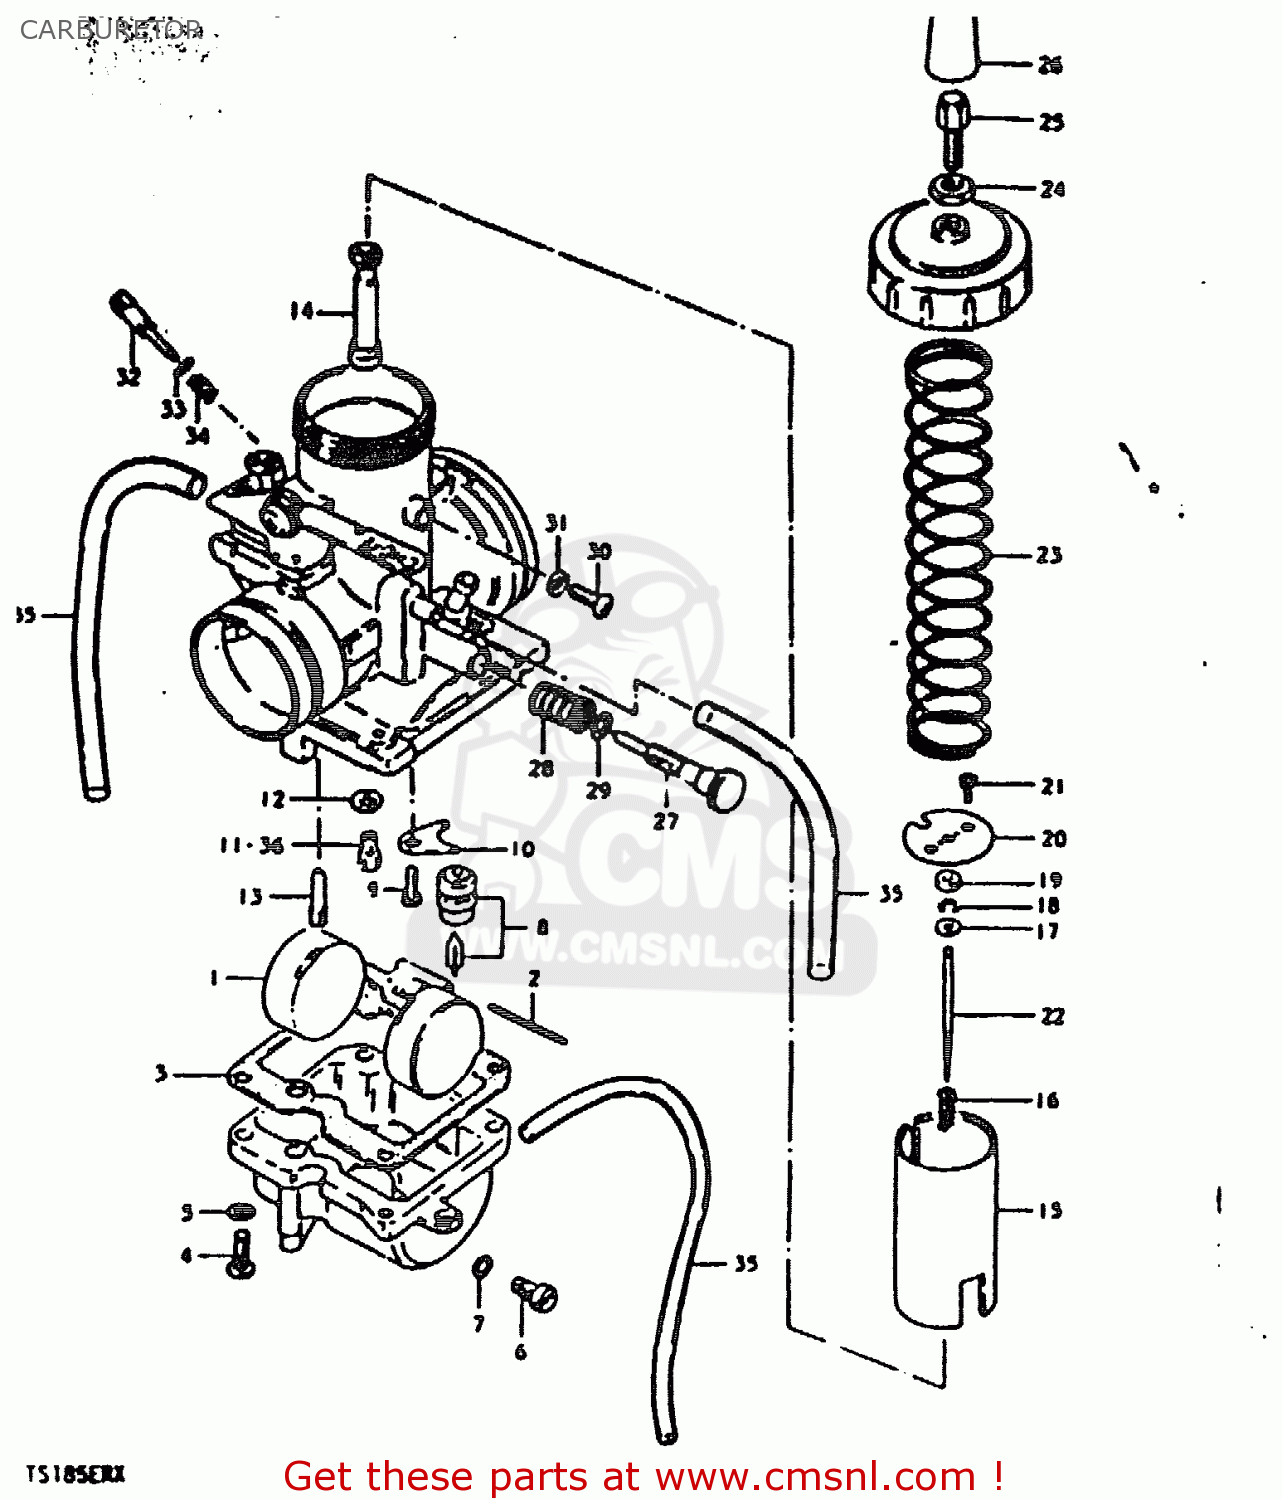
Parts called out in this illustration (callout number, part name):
1	FLOAT
2	PIN,FLOAT
3	GASKET,FLOAT CAHMBER (NAS)
4	SCREW
5	LOCK WASHER
6	PLUG
7	GASKET,DRAIN,PLUG (NAS)
8	VALVE ASSEMBLY,NEEDLE
9	SCREW
10	PLATE
11	JET
12	WASHER
13	JET
14	JET,NEEDLE
15	VALVE,THROTTLE
16	SPRING
17	WASHER,JET NEEDLE
18	CLIP
19	RING
20	PLATE
21	SCREW
22	NEEDLE,JET
23	SPRING, THROTTLE VALVE
24	NUT
25	ADJUSTER,CABLE
26	CAP
27	ADJUSTER
28	SPRING
29	O-RING
30	SCREW
31	RING
32	SCREW,PILOT AIR
33	O RING
34	SPRING
35	HOSE
36	JET
